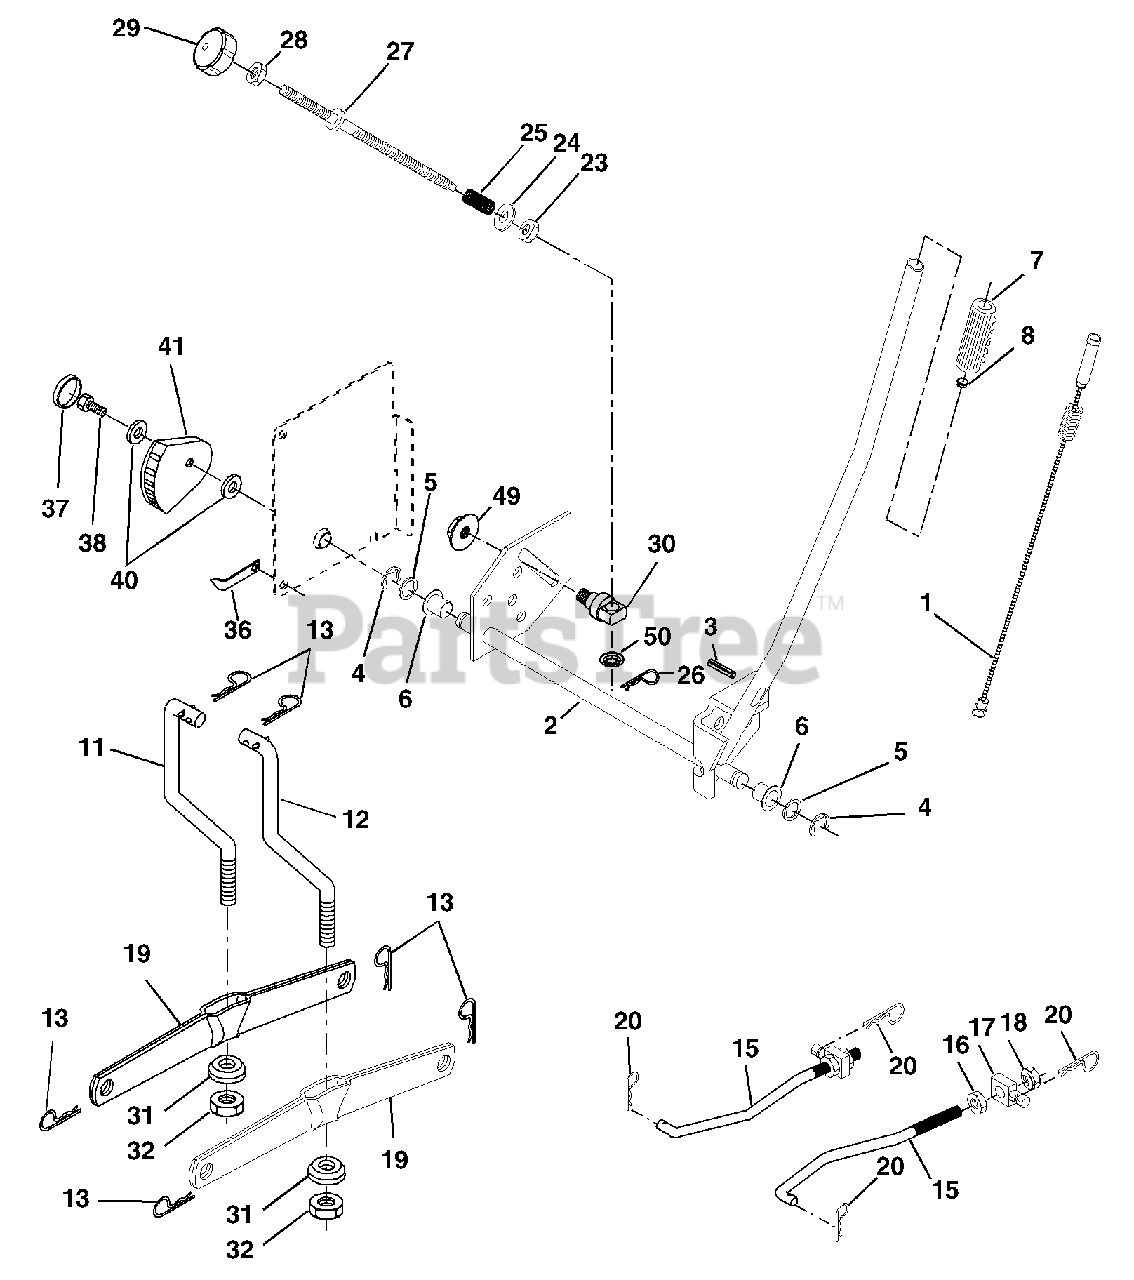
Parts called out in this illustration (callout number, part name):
1	Wire Asm Inner/Spring W/Plunger LT
2	Shaft Asm Lift RH w/Inf
3	Pin Groove 1 500 Zinc
4	E Ring #5133-62
5	Washer 21/32 X 1 X 21 Ga
6	Bearing Nylon Blk 629 Id
7	Grip Handle Fluted Blk
8	Button Plunger Black
11	Link Lift LH
12	Link Lift RH
13	Retainer Spring
15	Link Front
16	Nut Jam Hex 1/2-13 Unc
18	Nut Lock w/Wsh 1/2-13unc
19	Arm Suspension Rear
20	Retainer Spring
23	Nut Special
24	Washer 13/32 X 5/8 X 16 Ga
25	Spring 2-1/8"
26	Retainer Clip
27	Rod Adj Lift Zinc 7.49 Wrk Lg
28	Nut Hex Jam 3/8-16 Unc
29	Knob Inf 3/8-16 Unc Blk W/sym
30	Trunnion Infin Height
31	Bearing PVT Lift
32	Nut Crownlock 3/8-24
36	Indicator Height STLT
37	Plug Hole Blk 1.485/1.515 Dia.
38	Screw 5/16-18 x 1
40	Washer 11/32 x 1-1/2 10 Ga.
41	Scale Ind. Height Blk.
49	Nut Hex Flange Lock
50	Nut, Push Phos & Oil
